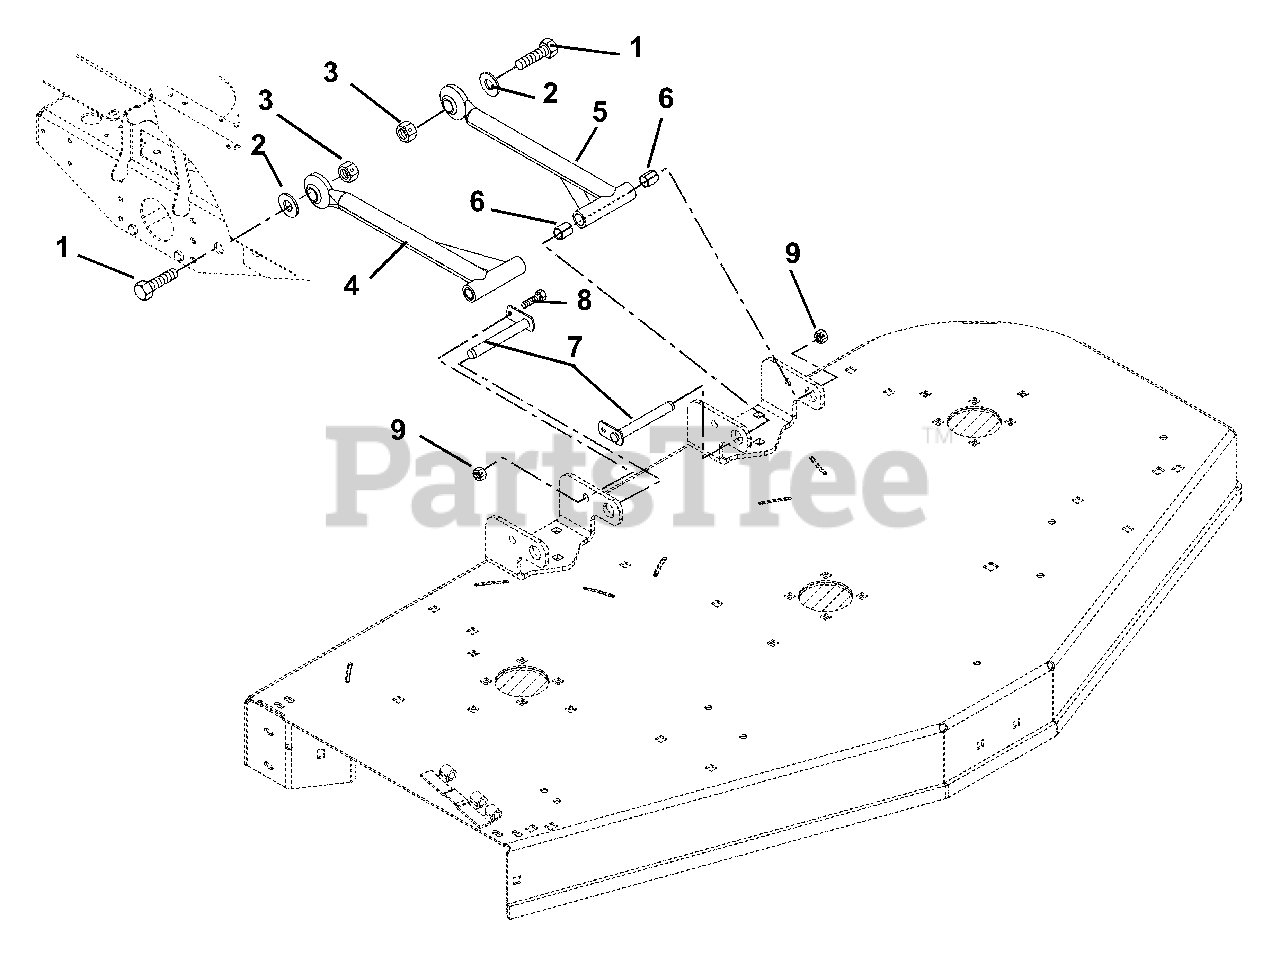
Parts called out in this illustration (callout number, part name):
1	BLT-HEX .875-9X3.00 GR5 YZ
2	BSHG-SLV .882X1.250X.531
3	NUT-LK-CTR .875-9 YWZC
4	ASSY, MOWER MOUNTING
5	MOWER MTG ARM - BLACK
6	BRG, .750 X .875 X 1.000
7	WELDMENT, MOWER MTG. PIN
8	@BLT-HEX .38-16X1.00 GR5 YWZC
9	@NUT-LK-NYL-FLG .38-16 YWZC
